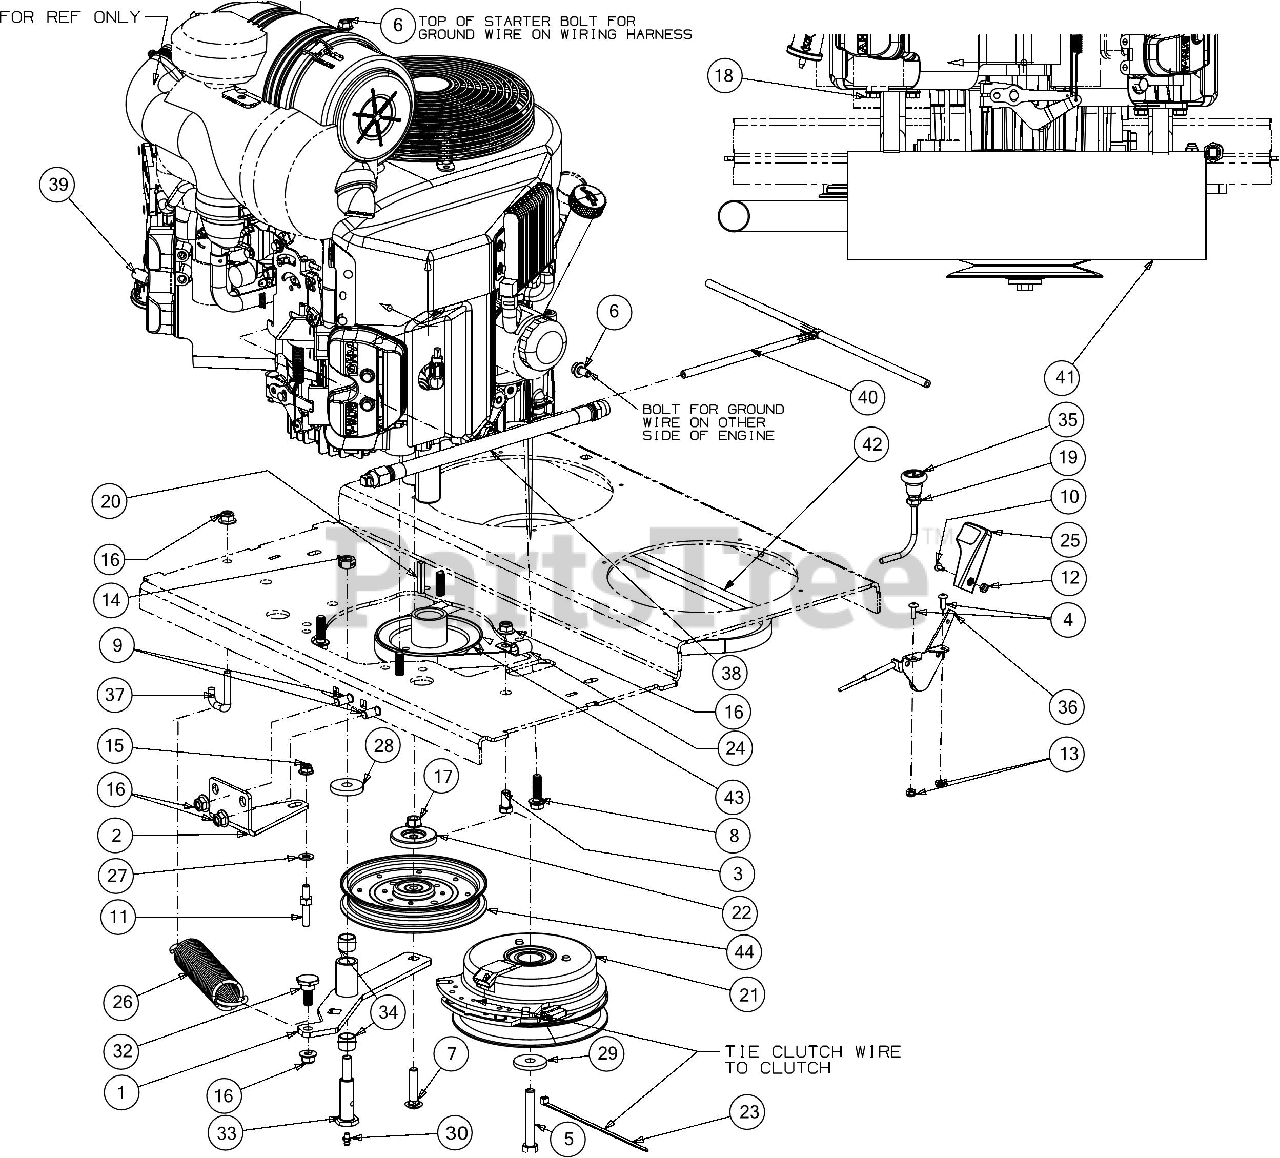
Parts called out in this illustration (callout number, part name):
1	TRANSMISSION IDLER BRACKET
2	RETAINER BRACKET
3	HEX SCREW 3/8-16 X .75
4	SCREW #10-24 X .62
5	SCREW 7/16-20:2.75 GR5
6	SCREW M8 X 1.25 X 16MM GR8.8
7	CARRIAGE BOLT 3/8-16 X 1.75 GR5
8	SCREW 3/8-16 X 1.25 GR5
9	CARRIAGE BOLT 3/8-16 X 1.00 GR5
10	SCREW #8-32X.38 LG
12	HEX NUT 8-32
15	FLANGE LOCK NUT 5/16-18
17	HEX LOCK NUT
18	HEX FLANGE NUT
19	HEX JAM NUT 3/8X24
20	SQUARE KEY 1/4 X 1.50
21	ELECTRIC PTO CLUTCH
22	PULLEY CAP
23	CABLE TIE 7"
24	J TYPE CLIP
25	THROTTLE CONTROL KNOB
26	EXTENSION SPRING
27	FLAT WASHER
28	FLAT WASHER 47 X 1.50 X .225
29	FLAT WASHER .45 X 1.5 X .172 HT
30	GREASE FITTING
32	SHOULDER SCREW .625 X .302 X 3/8-16
33	SHOULDER BOLT 7/16-14
34	SLEEVE BEARING
35	CHOKE CABLE
36	THROTTLE CABLE 42"
37	ROD SPRING HOOK
38	OIL DRAIN HOSE
39	FUEL HOSE LOW PERMEATION
40	ROLLOVER VENT HOSE ASSEMBLY
41	MUFFLER (KAWASAKI)
42	TRANSMISSION BELT
43	PULLEY - PUMP DRIVE
44	IDLER PULLEY
